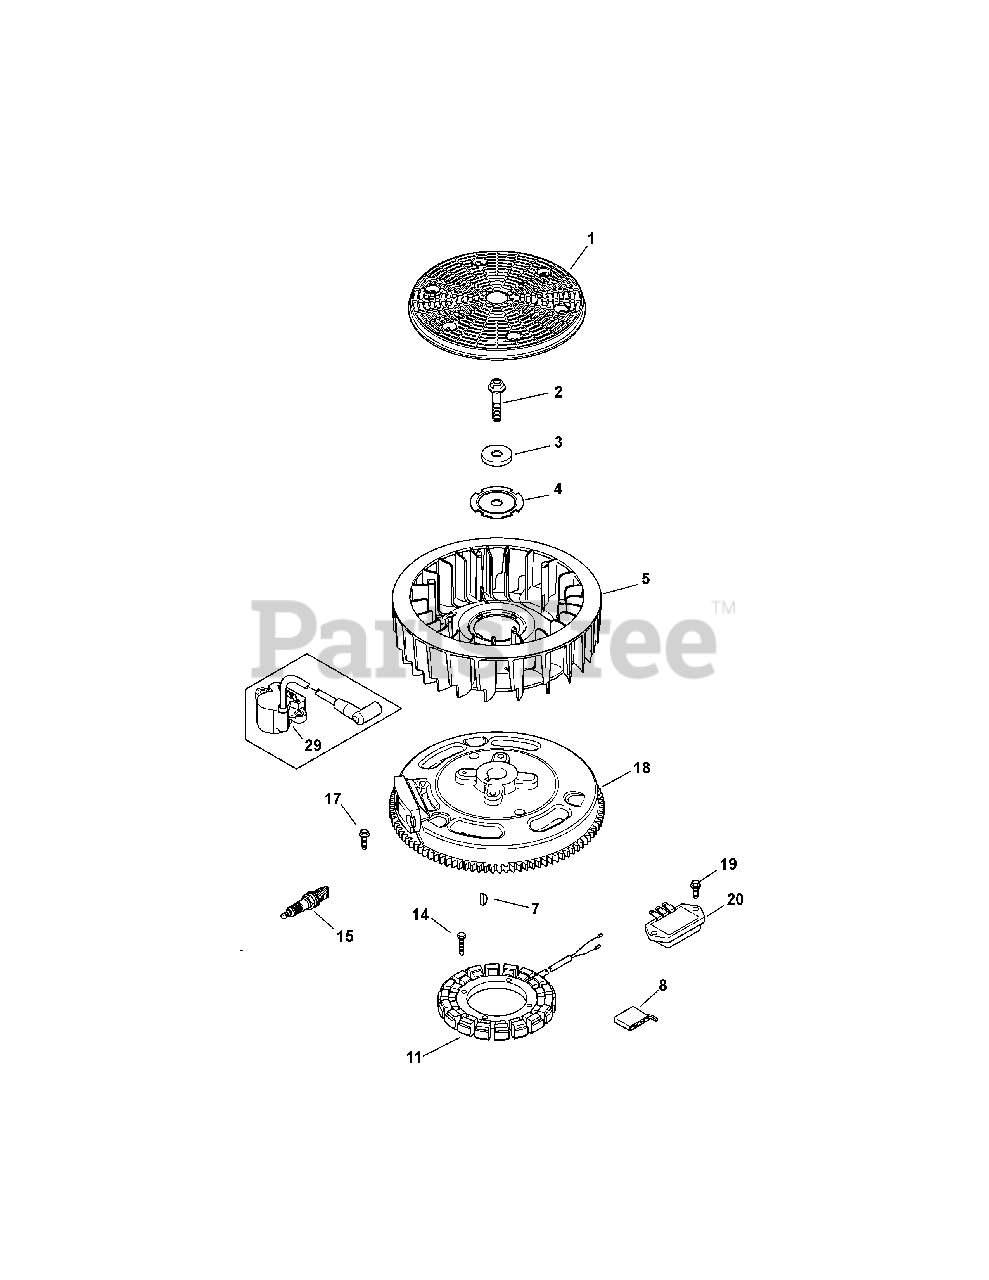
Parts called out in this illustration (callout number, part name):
2	Flg. Screw, M10 x 1.5 x 45
3	Flat Washer, 13/32
4	Fan Mounting Plate
5	Fan
7	Key, 3/16 x 5/8
11	15 Amp Stator Kit (Inc. KH-25-452-01-S)
14	Thd. Frm. Screw, M5 x 0.8 x 25
15	Spark Plug
17	Flg. Thd. Frm. Screw, M5 x .8 x 20
18	Flywheel Assembly
29	Spark Adv. Module Assembly
